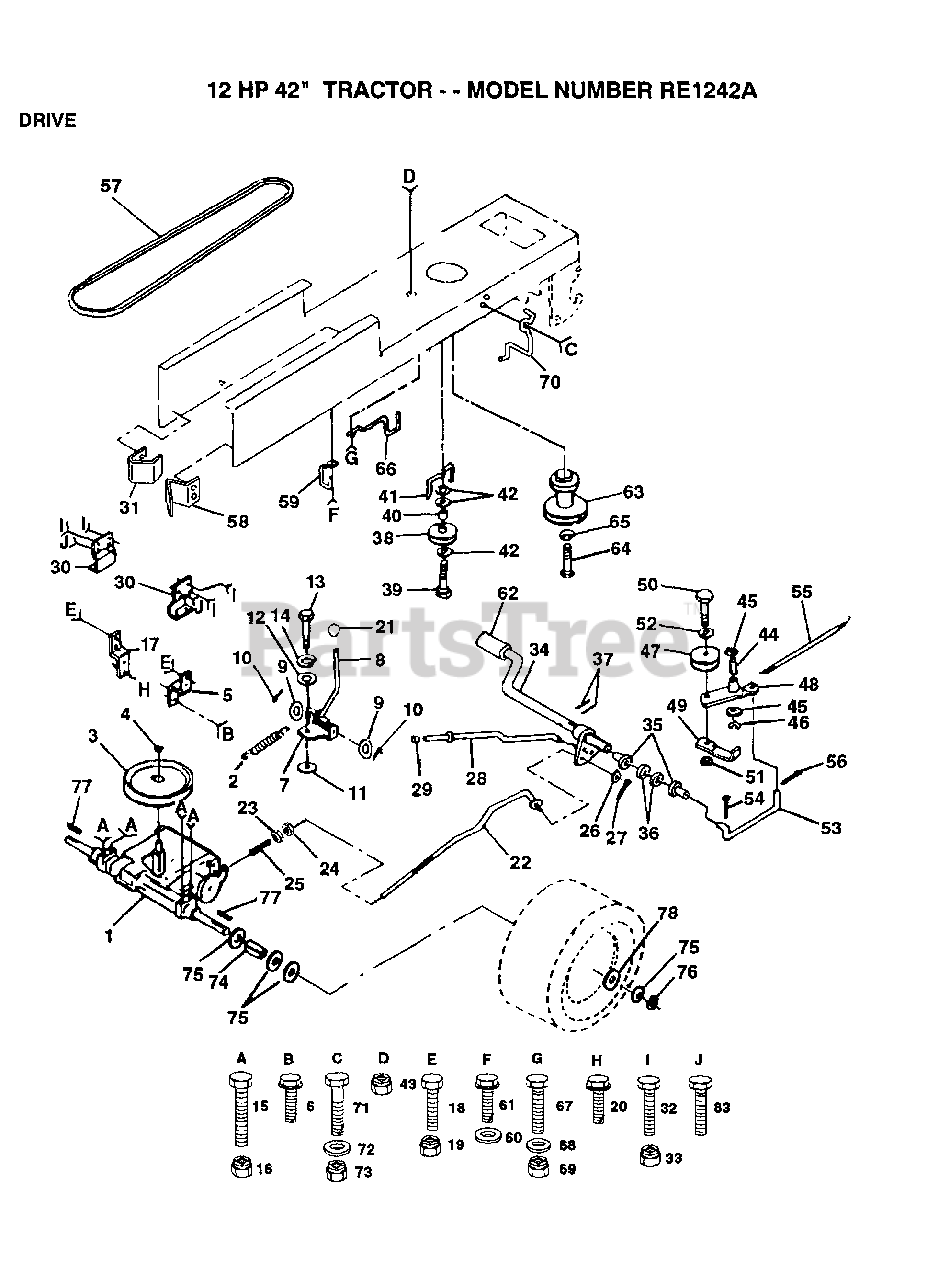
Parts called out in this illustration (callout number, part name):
3	PULLEY TRANS
5	STRAP TORQUE
6	SCREW
8	SHIFT ROD
9	WASHER
10	PIN COTTER 1/8
11	WASH-SHFT PLT LT
12	WASHER LT
14	LOCKWASHER
15	BOLT
17	STRAP TORQUE
20	SCREW
21	CONTROL KNOB LT
22	BRAKE ROD
23	NUT
24	NUT
25	SPRING ROD LT
26	WASHER
27	COTTER PIN
28	PARKING BRAKE ROD
30	TRANSAXLE MTG BKT
31	"KEEPER,BELT LH T"
32	BOLT
35	NYLON BEARING
36	WASHER LT
38	PULLEY.IDLER.FLAT
39	BOLT
40	SPACER T
41	BELT KEEPER LT
42	WASHER
44	"LY, BEARING"
45	WASHER LT
46	KLIP RING
48	ARM IDLER
49	RETAIN BELT
52	WASHER
53	"LINK, CLUTCH T"
54	COTTER PIN
55	"SPRING, RETURN LT"
56	COTTER PIN
58	"KEEPER,BELT RH T"
60	WASHER
61	SCREW
62	PEDAL COVER T
64	BOLT
65	LOCKWASHER
66	KEEPER.BELT.ENG.L
67	BOLT
68	WASHER
70	KEEPER BELT ENG
71	BOLT
72	WASHER
74	SPACER LT
75	WASHER
76	E-RING LT
77	SQUARE KEY
78	WASHER
83	SCREW
